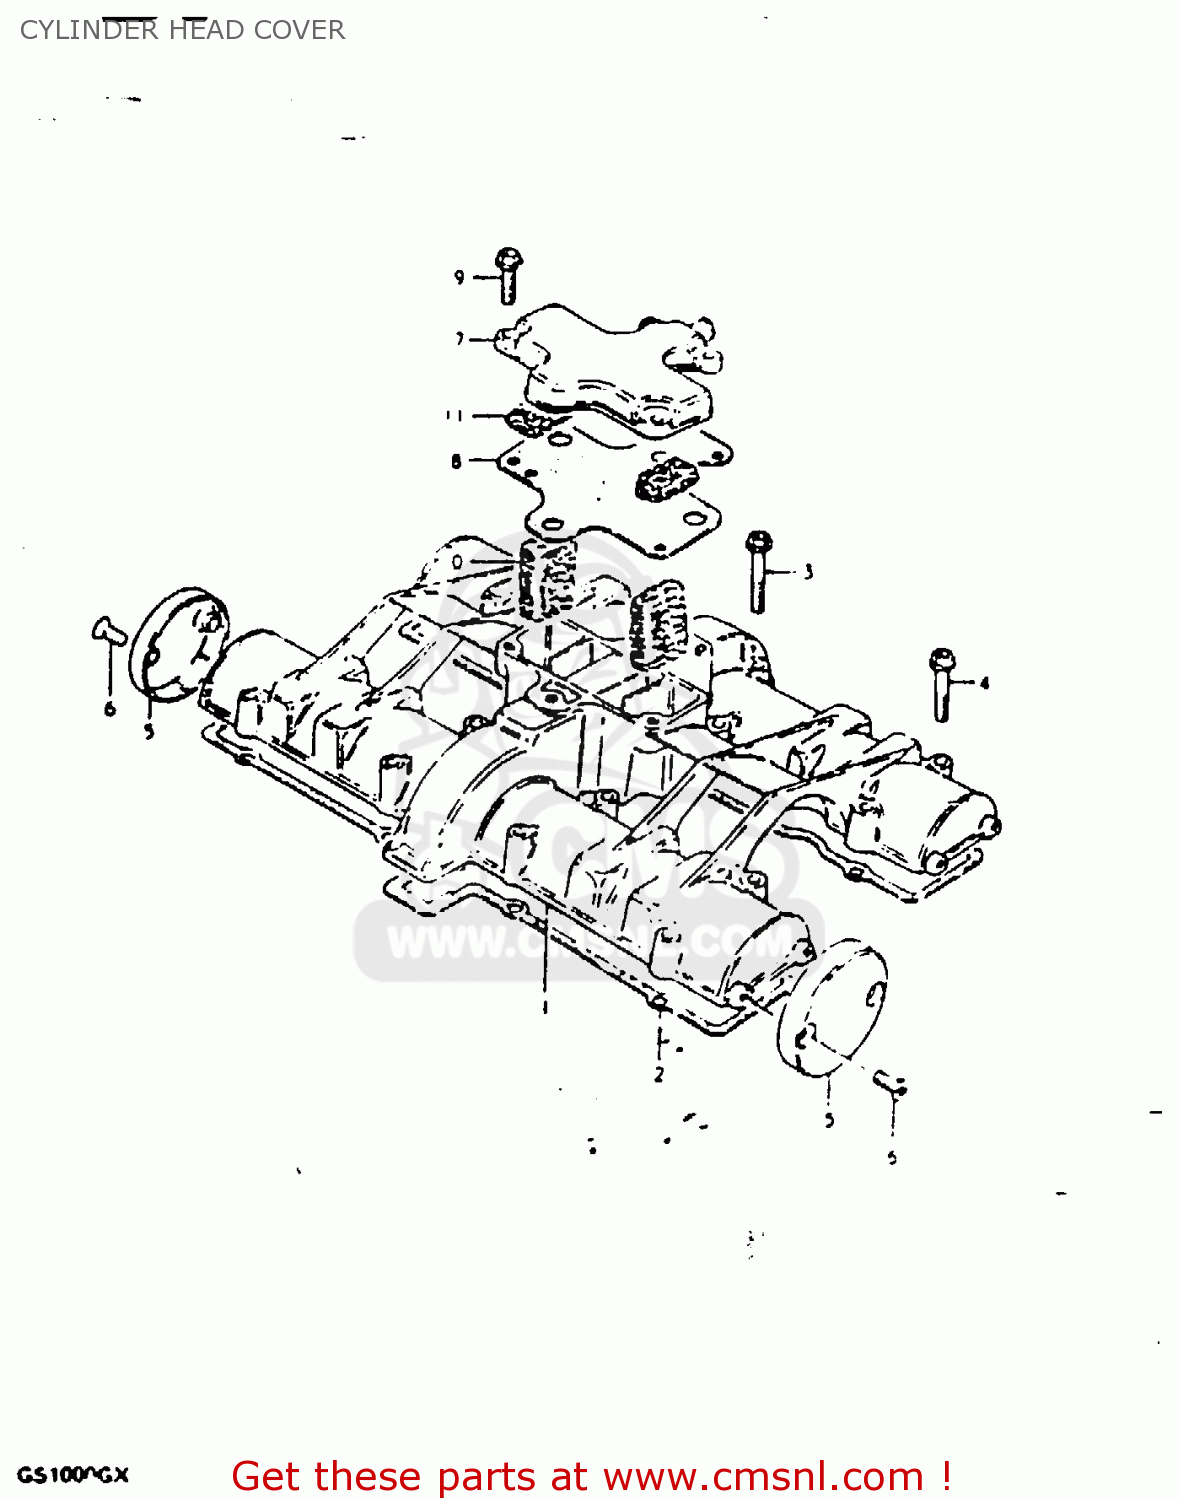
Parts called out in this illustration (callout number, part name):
1	COVER,CYLINDER HEAD
2	GASKET,CYLINDER HEAD COVER (MCA)
3	BOLT
4	BOLT 6X35
5	CAP,CYLINDER HEAD COVER
6	SCREW 5X12
7	COVER,BREATHER
8	GASKET (MCA)
9	BOLT
10	COVER,BREATHER
11	SEPARATOR,OIL BREATHER
